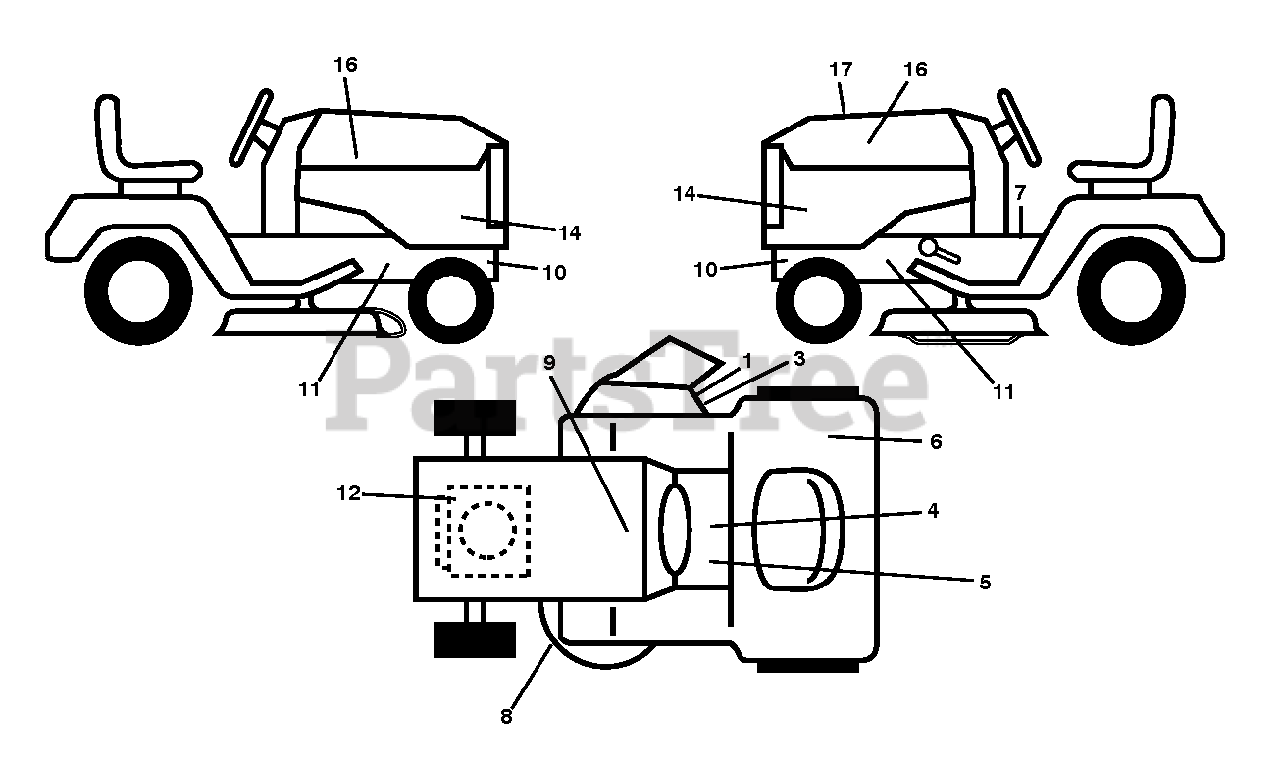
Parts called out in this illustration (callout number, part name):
1	DECAL.INTERNATIONL.CUTFINGER
3	DECAL, DEFLECT WARNING
4	DECAL PARK BRAKE
5	LABEL
6	Decal, Fender 100 DB/CE
7	DECAL
8	DECAL V BELT SCHEMATIC
9	DECAL BTRY SYMBOLS
12	DECAL
16	DECAL.BADGE.170MM.TEXTLOGO.
